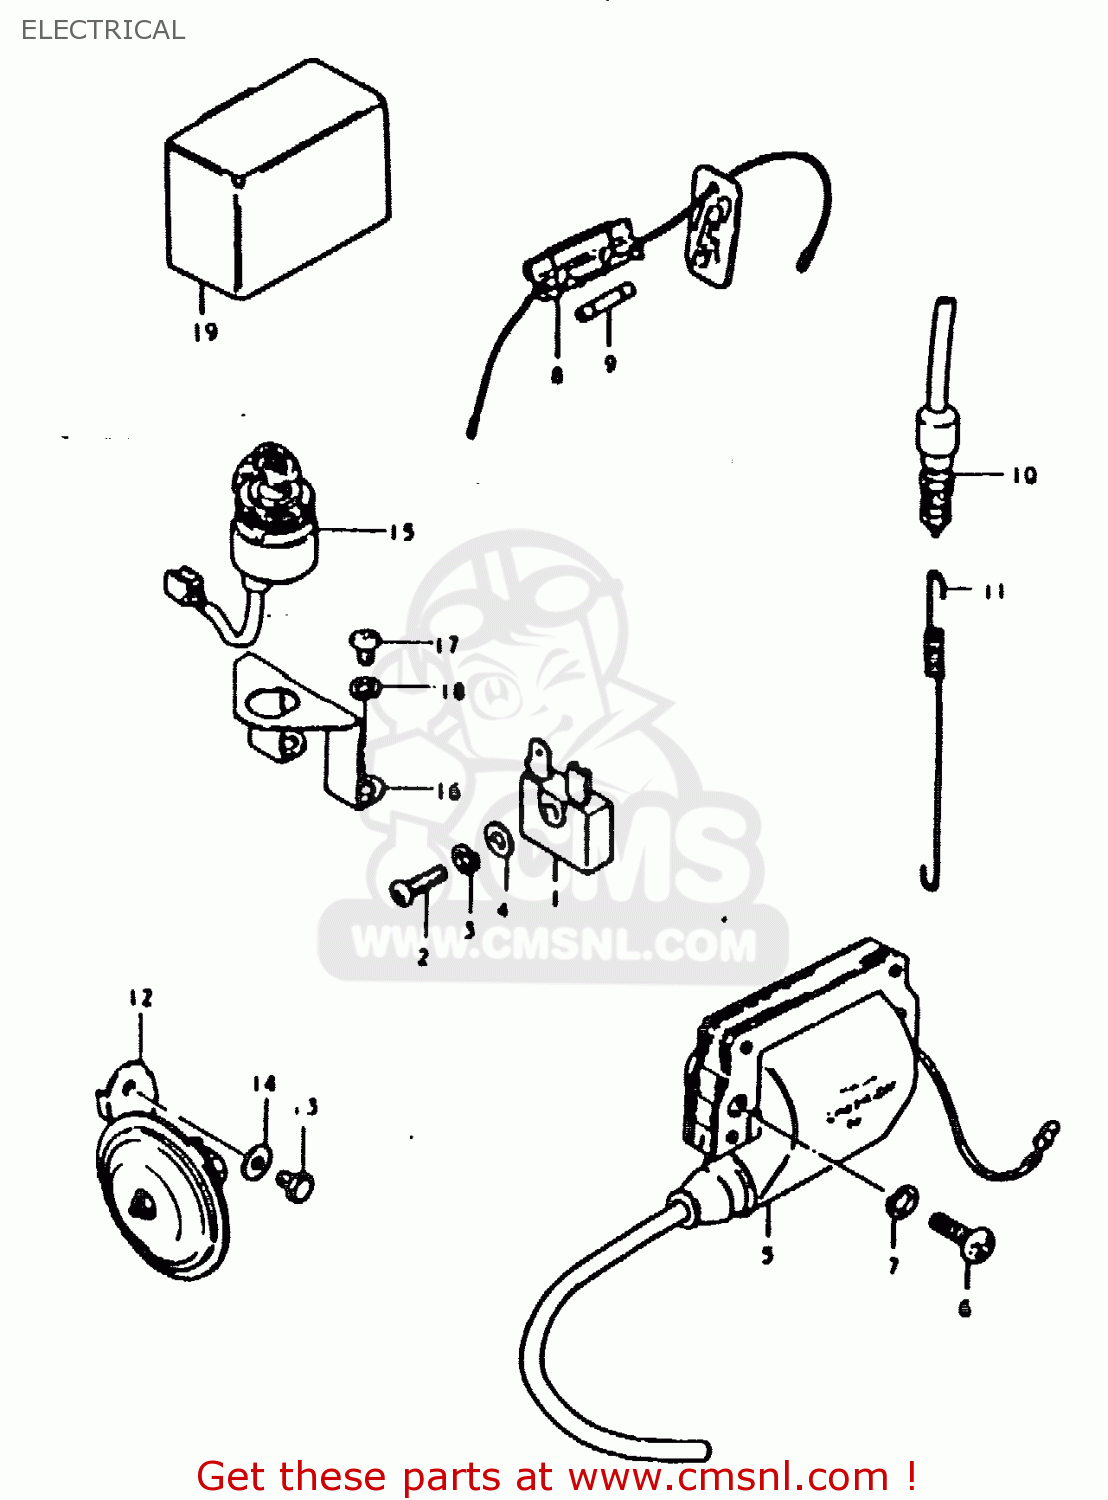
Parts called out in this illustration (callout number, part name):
1	RECTIFIER ASSEMBLY
2	SCREW 5X20
3	LOCK WASHER
4	WASHER
5	COIL ASSEMBLY,IGNITION
6	SCREW
7	LOCK WASHER
8	BOX ASSEMBLY,FUSE
9	FUSE(10A)
10	SWITCH ASSEMBLY,STOP LAMP
11	SPRING
12	HORN ASSEMBLY
13	BOLT
14	WASHER
15	SWITCH ASSEMBLY,IGNITION
16	BRACKET, IGNITION SWITCH
17	SCREW
18	LOCK WASHER
19	RELAY, TURN SIGNAL
